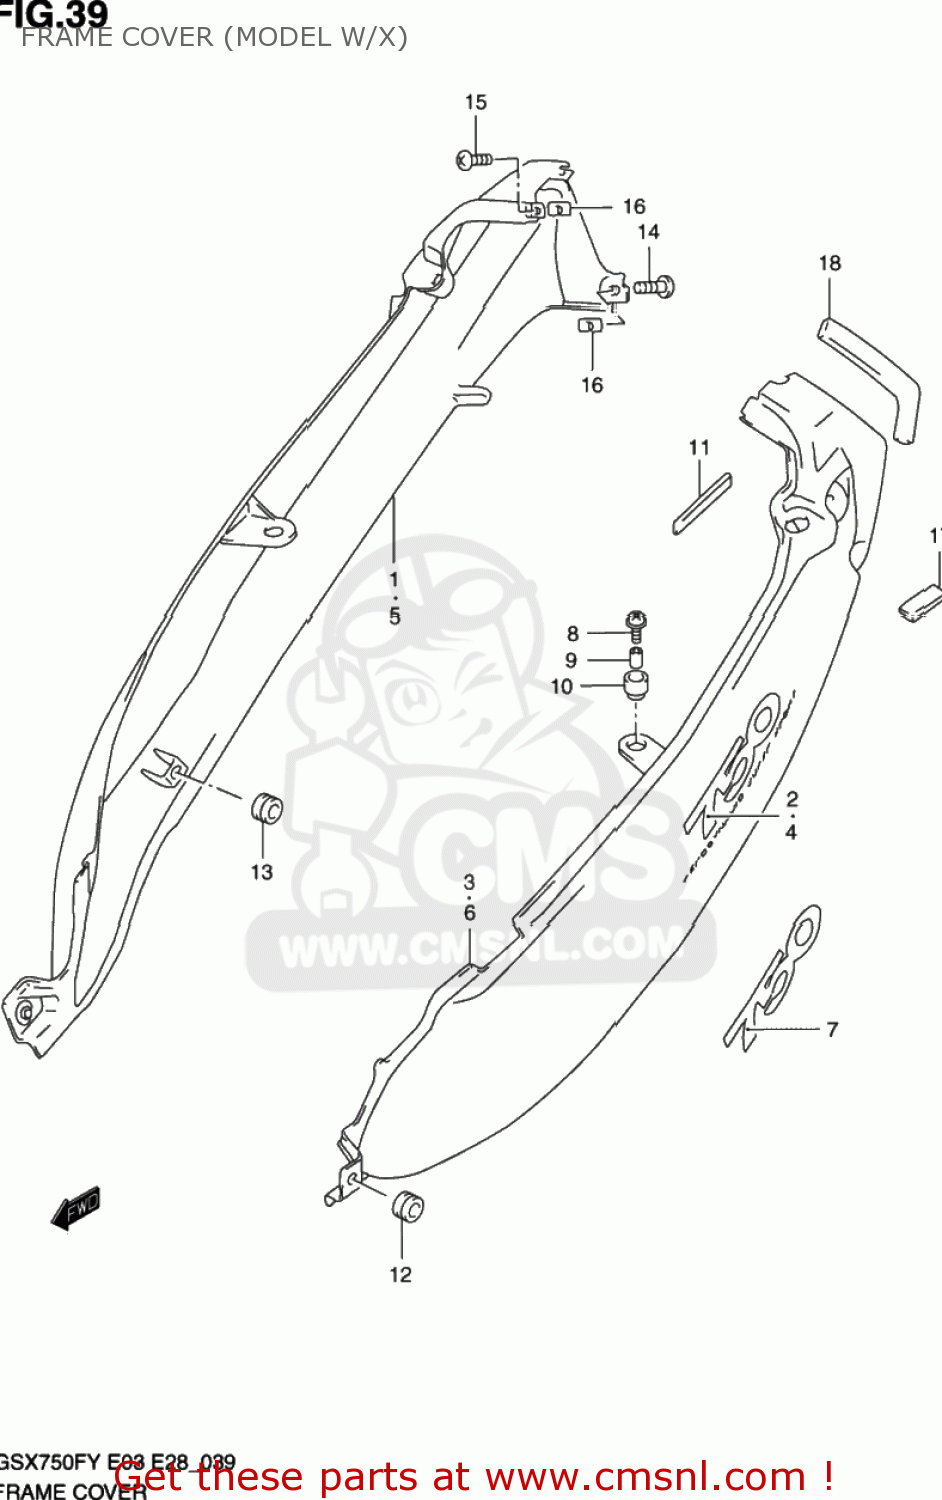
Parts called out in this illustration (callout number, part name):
1	COVER,FRAME,R(BLACK)
2	EMBLEM,FRAME COVER,R
3	COVER,FRAME,L(BLACK)
4	EMBLEM,FRAME COVER,L
5	COVER,FRAME,R(BLUE)
6	COVER,FRAME,L(BLUE)
7	EMBLEM,FRAME COVER
8	SCREW(6X20)
9	SPACER(6.5X10X9.4)
10	CUSHION
11	CUSHION,UNDER COWLING NO.1
12	CUSHION
13	CUSHION
14	SCREW
15	SCREW
16	NUT
17	CUSHION
18	CUSHION,FRAME COVER
